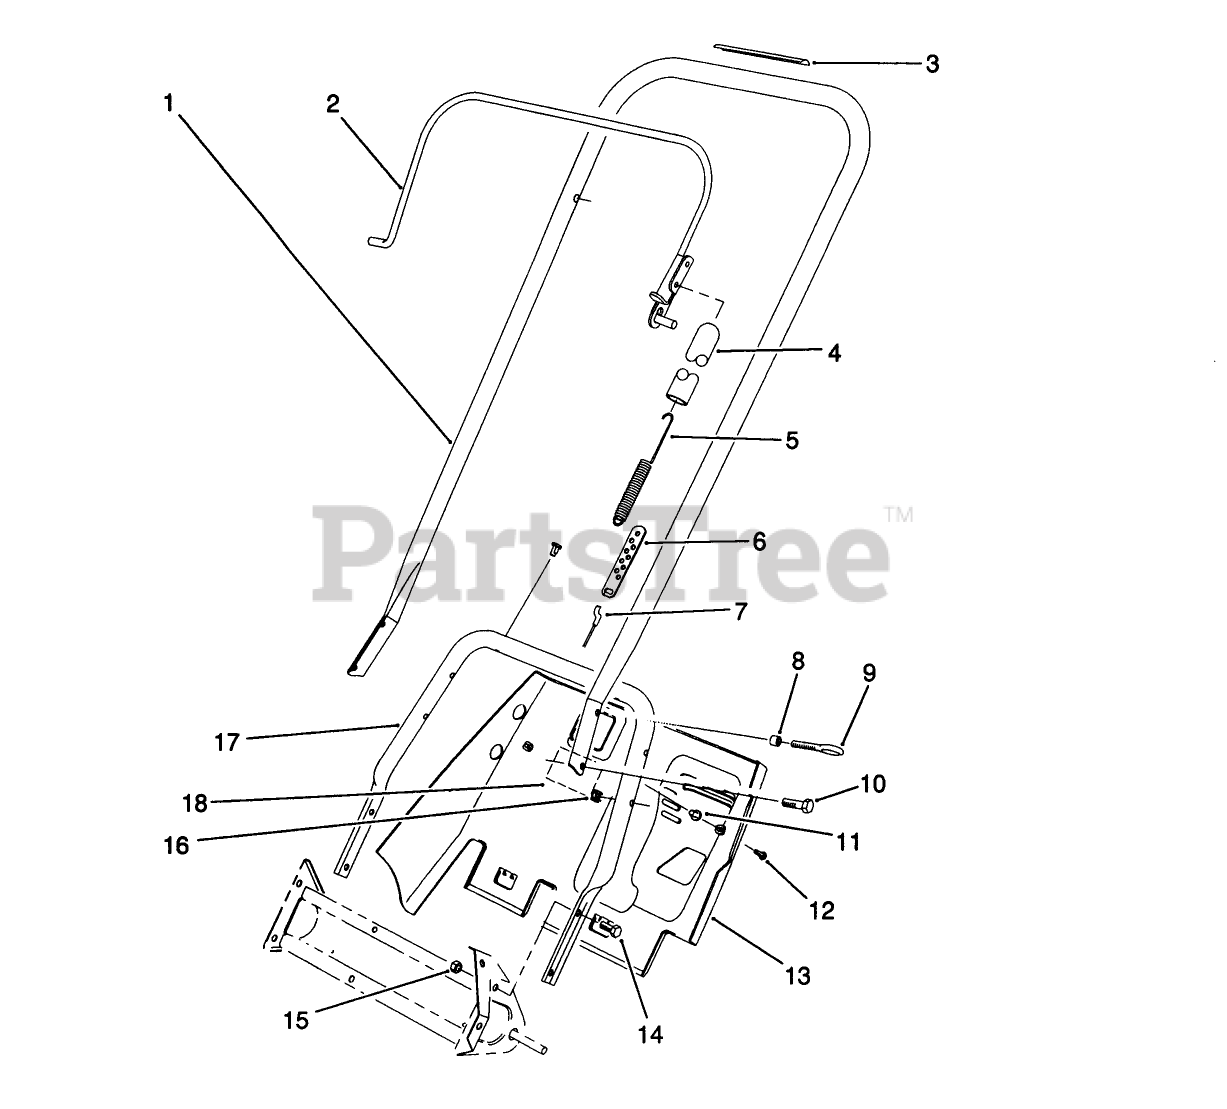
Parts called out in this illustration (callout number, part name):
4	COVER-SPRING
5	SPRING-CLUTCH
7	CABLE-CLUTCH
8	SPACER-BLADE, ROTOR
9	BOLT-EYE
11	EXPANSION TYPE FASTENER
12	SCREW-SHWH, THREAD FORMING
14	SCREW-HH
15	NUT-LOCK, NI
16	TINNERMAN NUT
